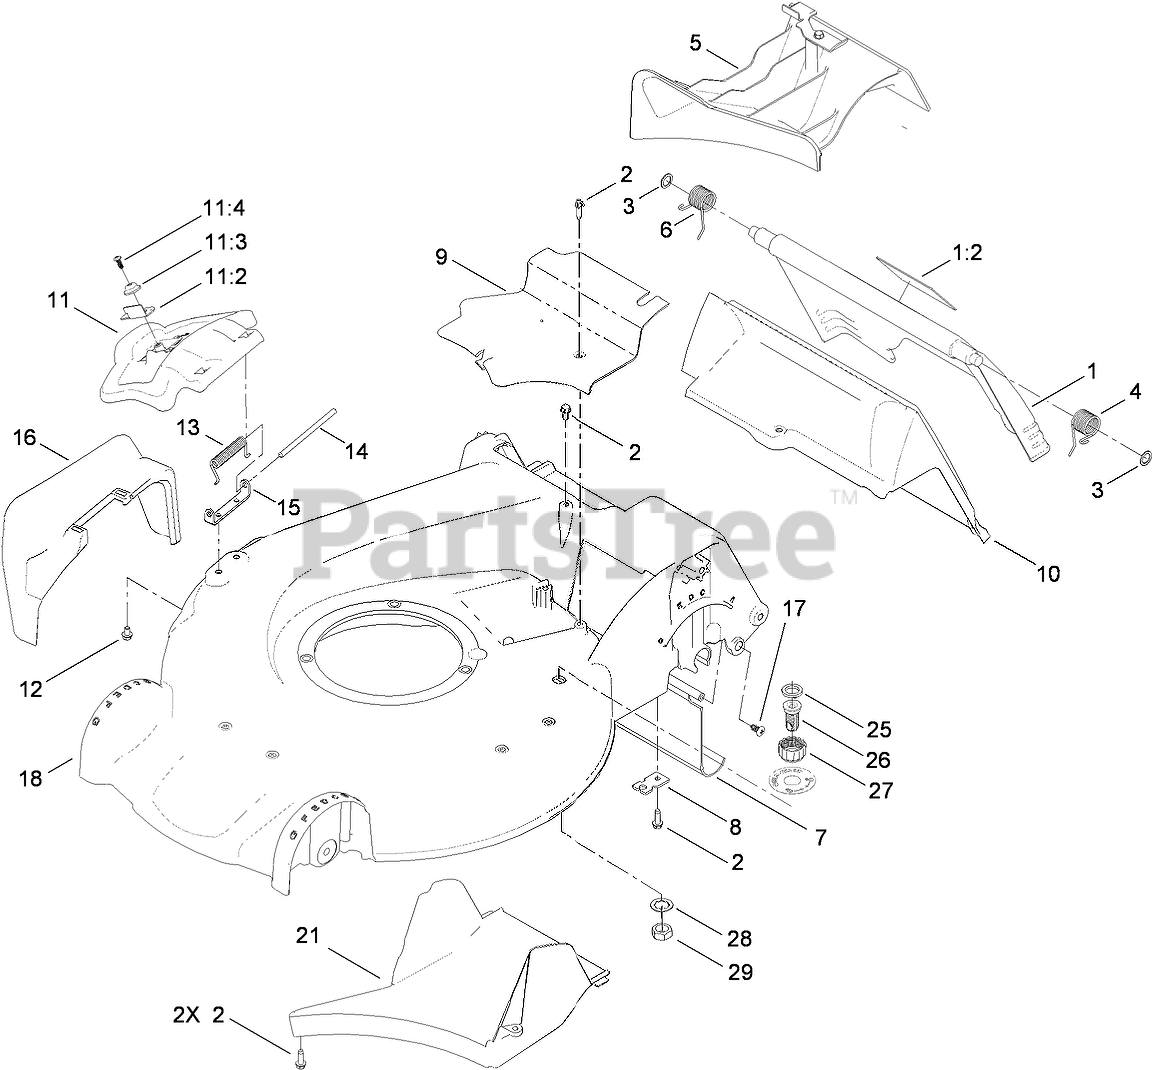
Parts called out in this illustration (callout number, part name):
1	REAR DOOR ASM
1:2	DECAL-WARNING
2	SCREW-HWHTF
3	WASHER-NYLON
4	SPRING-TORSION
5	MULCH PLUG ASM
6	SPRING-TORSION
7	SHIELD-TRAILING
8	BRACKET-CABLE, TRACTION
9	COVER-BELT
11	DISCHARGE DOOR ASM
11:2	LATCH-DOOR
11:3	CAP-DOOR
11:4	SCREW-PLASTITE
12	SCREW-HWH
13	SPRING-TORSION
14	ROD-COVER
15	BRACKET-COVER
16	CHUTE-DISCHARGE, SIDE
17	SCREW-PTH
18	HOUSING ASM
21	TUNNEL-DISCHARGE
25	WASHER-SEAL, WASHOUT PORT
26	PORT-WASHOUT
27	COUPLING-HOSE, WASHOUT PORT
28	WASHER-TOOTH, INTERNAL
29	NUT-JAM
